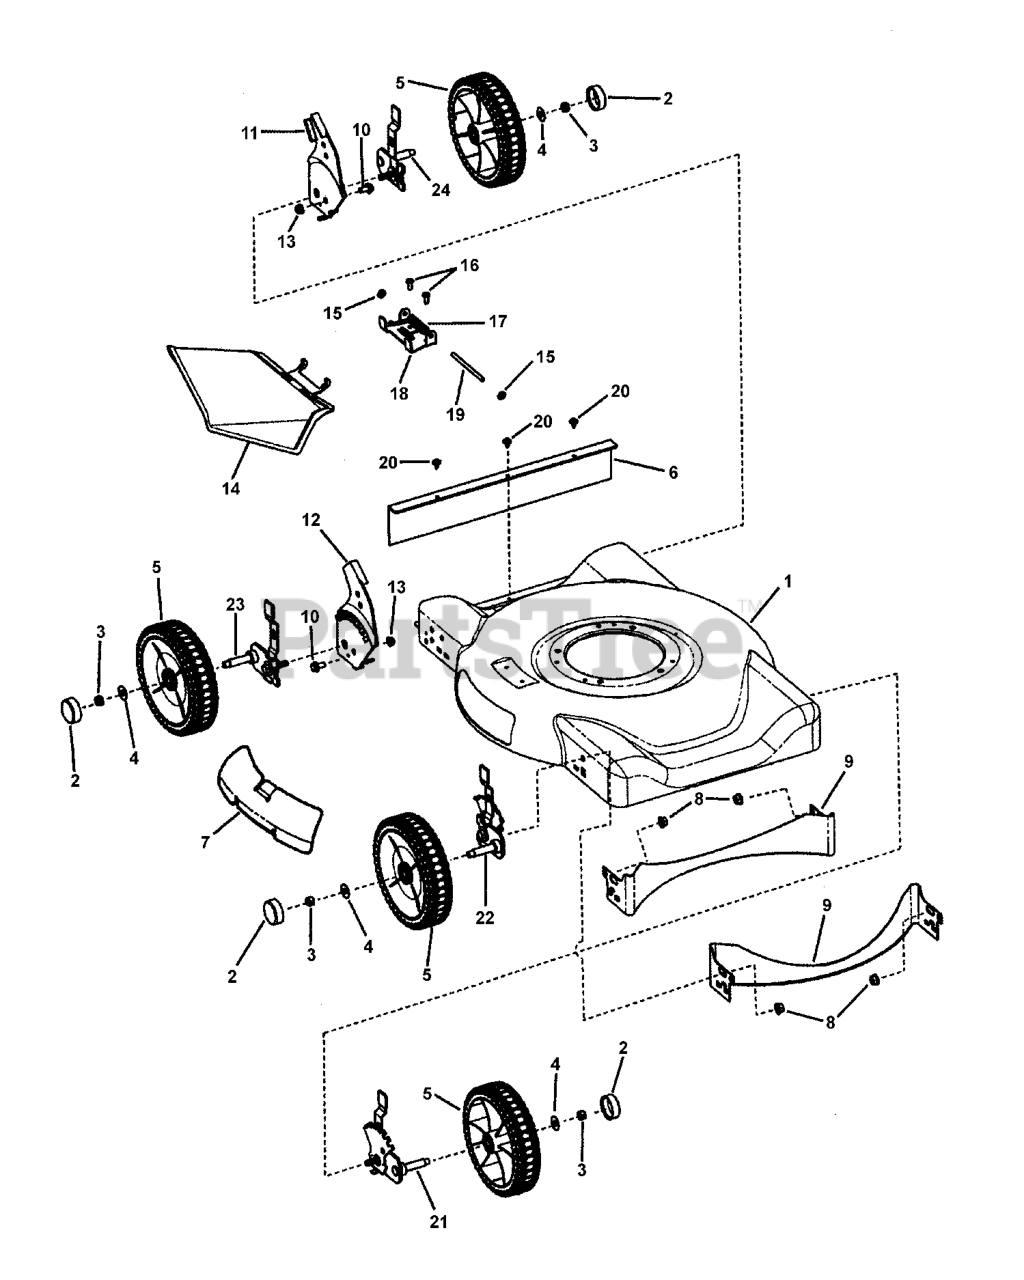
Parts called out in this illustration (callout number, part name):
1	DECK, 22" WBM, Side Discharge
2	HUBCAP, Round, Black
3	NUT, 3/8-16 Hex Center Lock YZ
4	WASHER, 1" O.D. x .387 I.D. Flat
5	ASSY, Wheel, 8" x 2" Idle, w/Db Tread, Brute Yellow
6	GUARD, Rear
7	PLATE, Mulch
8	NUT, 3/8-16 Hex Flange Lock, GR 5
9	BAFFLE, 22" Side Discharge
10	BOLT, 5/16-18 x 5/8" Hex Flange Lock
11	BRACKET, Lower Handle, LH Low Cost
12	BRACKET, Lower Handle, RH Low Cost
13	NUT, 5/16-18 Hex Flange Lock, BZ
14	CHUTE, Plastic S/D
15	PUSHNUT, 1/4"
16	SCREW, 1/4-20 x 11/16" Pan Head Self-Tap (Torx)
17	SPRING, Torsion, Chute
18	BRACKET, Chute Low Cost
19	ROD, Pivot, Mulch Cover
20	SCREW, #10-24 x 1/2" Hex Washer Self-Tap - Sems
21	ASSY, HOC, Left Front, 7 Position
22	ASSY, HOC, Right Front, 7 Position
23	ASSY, HOC, Right Rear, 7 Position
24	ASSY, HOC, Left Rear, 7 Position
